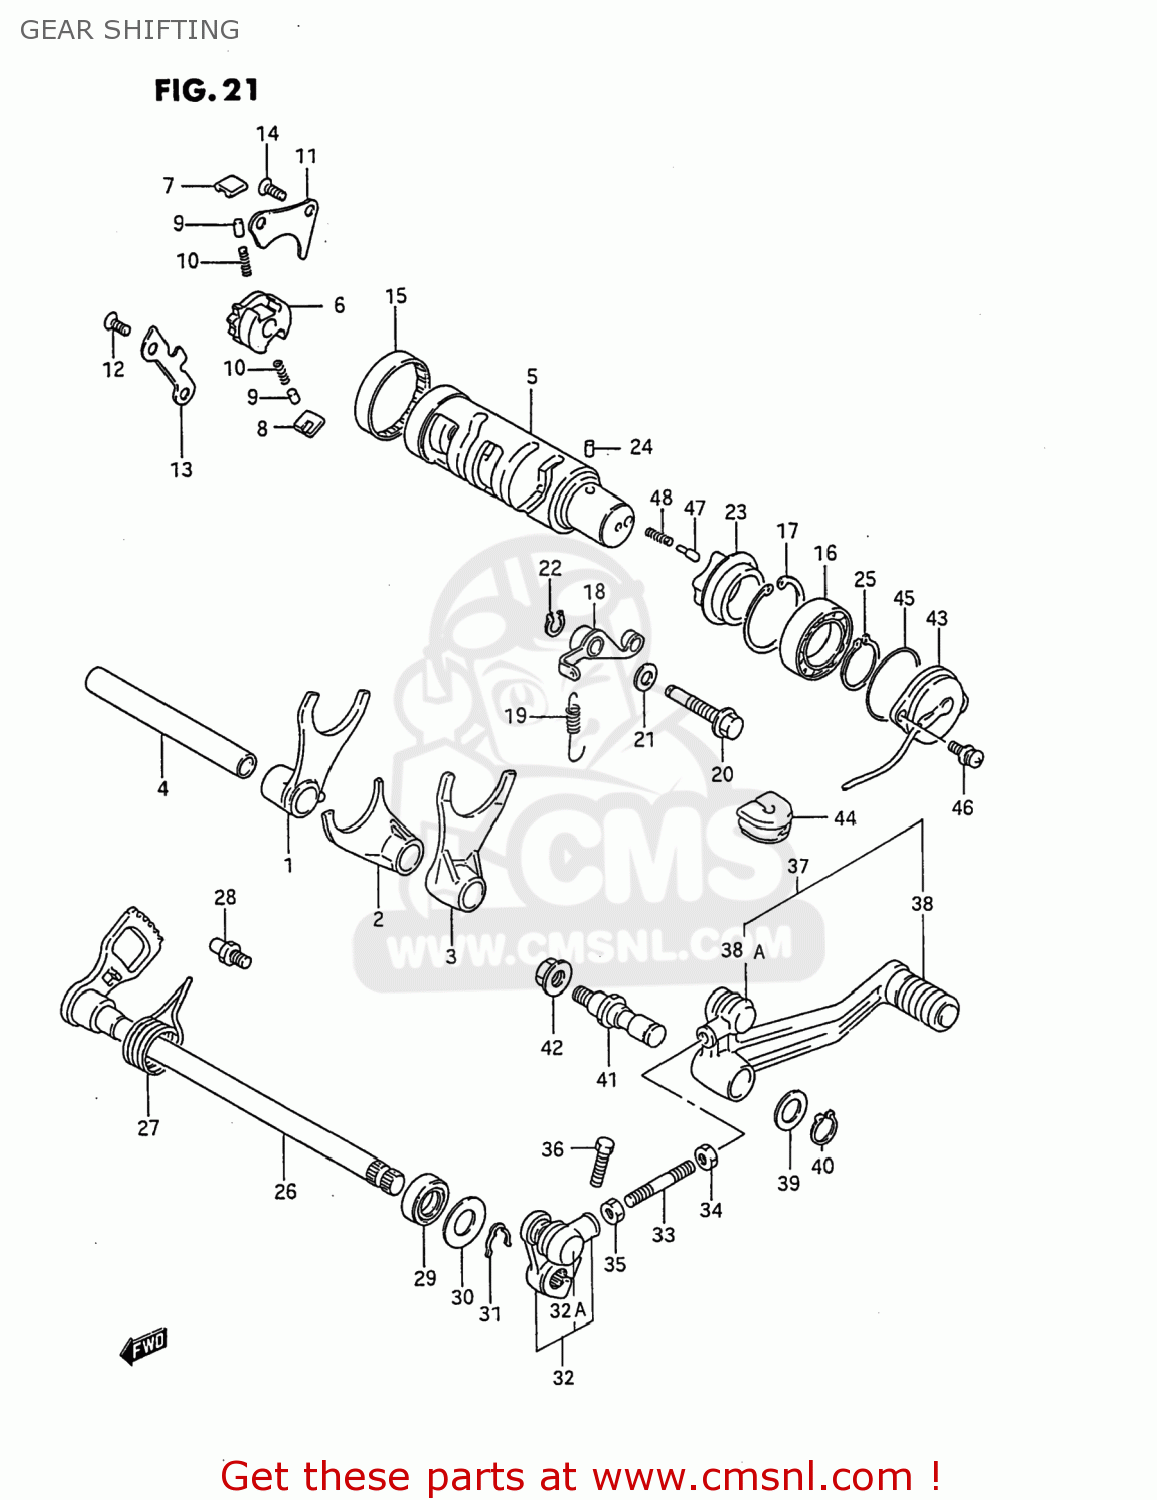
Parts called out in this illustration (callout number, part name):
1	FORK,GEAR SHIFT NO.1
2	FORK,GEAR SHIFT NO.2
3	FORK,GEAR SHIFT NO.3
4	SHAFT,GEAR SHIFT FORK(L:128)
5	CAM,GEAR SHIFT
6	GEAR,GEARSHIFT CAM DRIVE
7	PAWL,GEAR SHIFT NO.1
8	PAWL,GEAR SHIFT NO.2
9	PIN(5X8)
10	SPRING
11	LIFTER,GEAR SHIFT PAWL
12	SCREW
13	GUIDE,GEAR SHIFT CAM
14	SCREW
15	BEARING(43X49X12)
16	BEARING
17	CIRCLIP
18	STOPPER,GEAR SHIFT CAM
19	SPRING
20	SHAFT,GEAR SHIFT CAM STOPPER
21	GASKET(10X14X3.6) (NAS)
22	CIRCLIP
23	PLATE,STOPPER
24	PIN
25	CIRCLIP
26	SHAFT,GEAR SHIFT
27	SPRING
28	STOPPER,GEAR SHIFT CAM
29	OIL SEAL
30	WASHER (12.5X27X1.6)
31	CIRCLIP,12 MM
32	ARM,GEAR SHIFT LINK
32A	COVER,DUST
33	ROD,GEAR SHIFT LINK
34	NUT
35	NUT
36	BOLT
37	LEVER ASSY,GEAR SHIFT
38	RUBBER,GEAR SHIFT PEDAL
38A	COVER,DUST
39	WASHER(12.5X20X1)
40	CIRCLIP,12 MM
41	SHAFT,GEAR SHIFT LEVER
42	NUT
43	TERMINAL BASE ASSY,NEUTRAL
44	GROMMET,LEADWIRE
45	O RING(D:2.4,ID:35.5)
46	SCREW
47	PIN(5X15.5)
48	SPRING
